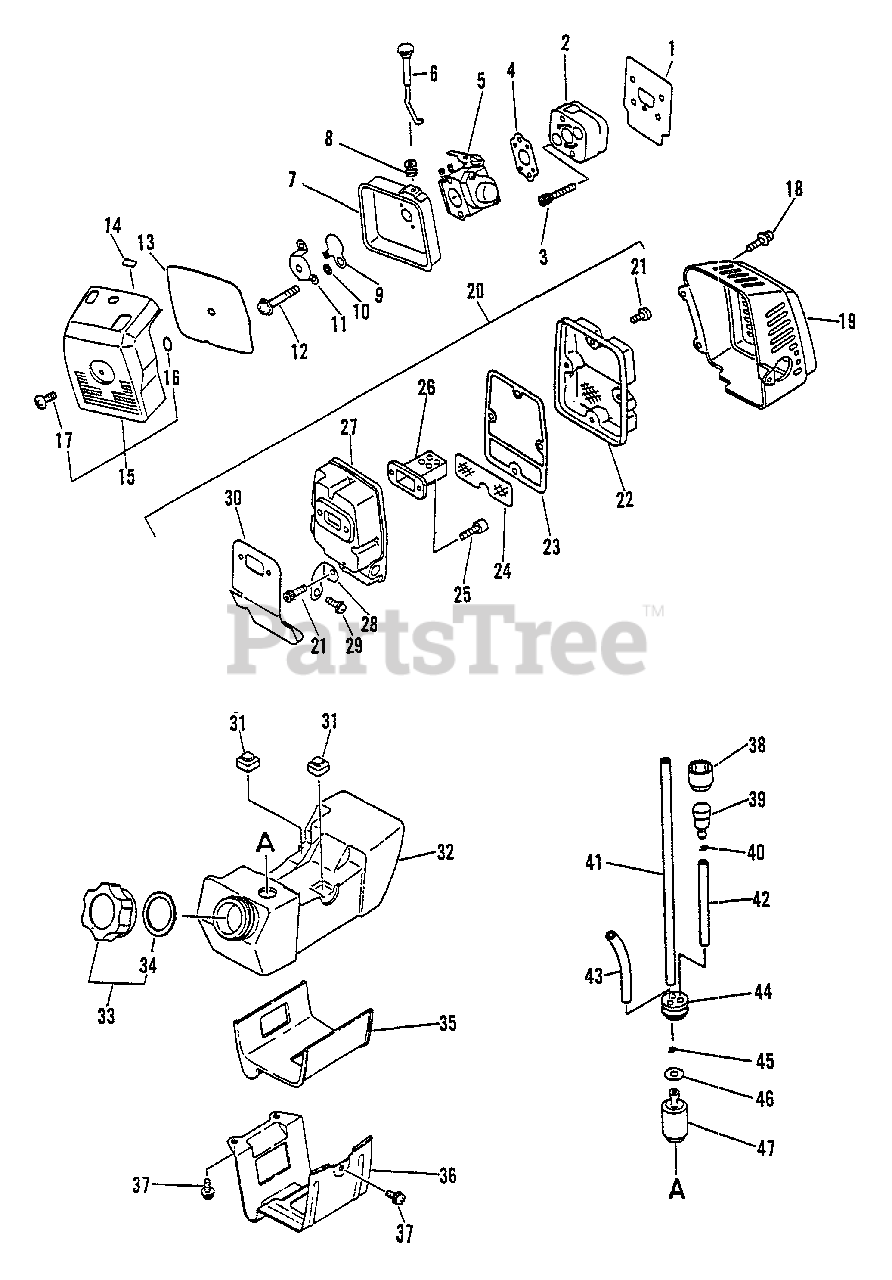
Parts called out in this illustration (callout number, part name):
1	GASKET, INTAKE
2	INSULATOR, INTAKE
3	BOLT 5×25
4	GASKET, INTAKE
5	CARBURETOR - C1U-K21A
6	ROD, CHOKE
7	CASE, AIR FILTER
8	GROMMET, CHOKE
9	SHUTTER, CHOKE
10	WASHER 5.2×8×0.8T
11	PLATE, PREVENT
12	SCREW 5×45
13	FILTER, AIR
13	FILTER, HEAVY-DUTY AIR
14	LABEL, CHOKE
15	AIR FILTER COVER ASSY
16	O-RING 3
17	THUMBSCREW
18	SCREW 4×8
19	COVER, MUFFLER
20	MUFFLER ASSY
21	BOLT 5×14
22	COVER, MUFFLER
23	GASKET, EXHAUST
24	SCREEN, SPARK ARRESTER
25	BOLT M5×18
26	SILENCER
27	MUFFLER
28	BRACKET, MUFFLER
29	SCREW 5×10
30	GASKET, MUFFLER
32	TANK, FUEL
33	CAP ASSY
34	GASKET, FUEL CAP
36	BRACKET, FUEL TANK
37	SCREW 5×12
38	HOLDER, VENT
39	VENT ASSY
40	CLIP 6 MM
41	PIPE, FUEL 3x-5x-180
42	PIPE, FUEL VENT 3×5×60
43	PIPE, FUEL RETURN 3×6×90 MM CLEAR
44	GROMMET, FUEL
46	WASHER 5.5×12×0.8
47	FILTER, FUEL
